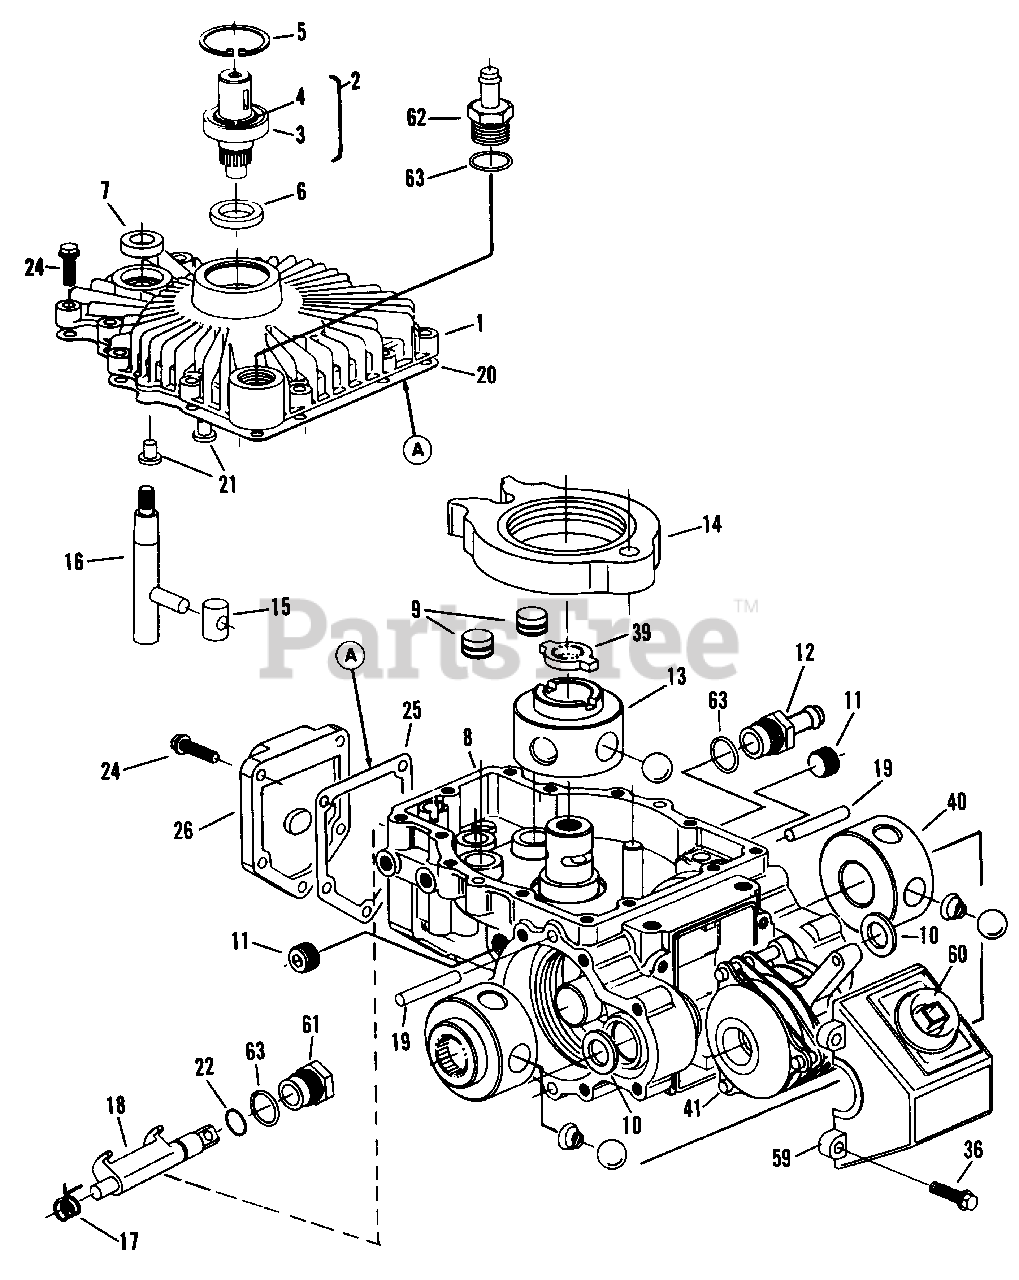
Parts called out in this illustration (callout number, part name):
1	COVER SUBASSY., Top (use with 1702247 shaft)
1	COVER SUBASSY., Top (use with 1705978 shaft)
2	SHAFT, Input, .75" Dia. (use with 1702706 cover)
2	SHAFT, Input, 17mm (.67") Dia. (use with 1705977 cover)
5	RING, Retainer, Internal
6	SEAL, Oil
8	HOUSING, CW
9	PISTON, Quieting
10	SEAL, Lip, Radial
11	PLUG, Socket, Pipe
13	PUMP, Rotor, Ball
16	CONTROL SHAFT
17	SPRING, Dump Valve
20	GASKET COVER (See "A" Below)
24	CAPSCREW, Hex, Flange, 1/4-20
25	GASKET, Valve Cover (See HA" Below)
26	COVER, Valve
36	SCREW, 1/4-20 Self Tap
40	MOTOR, Rotor, Ball
41	BRAKE ASSY., Parking
59	COVER, Parking Brake
62	ADAPTER, Resv. 3/8"
63	O-RING, Fitting
A	GASKET OVERHAUL KIT (Incl. Ref. Nos. 20, 25 & 23-next page)
